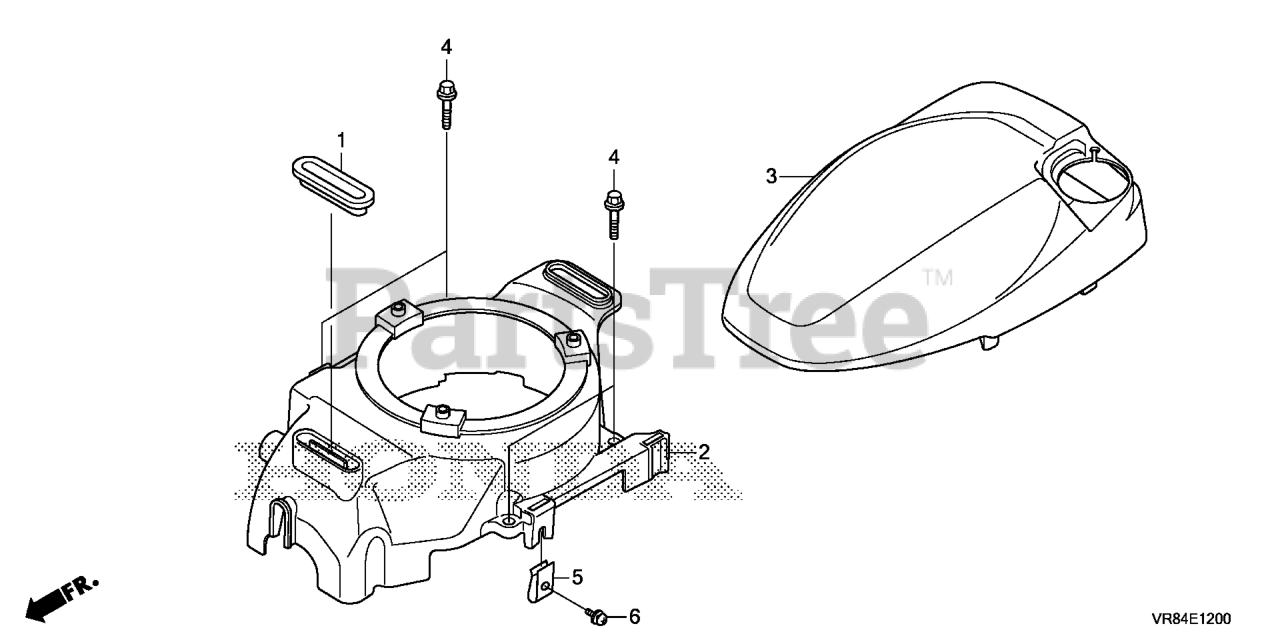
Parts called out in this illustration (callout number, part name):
1	RUBBER A, TANK MOUNTING
2	COVER, FAN
3	COVER, TOP *R280* (POWER RED)
4	BOLT, FLANGE (6X23)
5	NUT, SPRING (5MM)
6	SCREW-WASHER (5X8)
